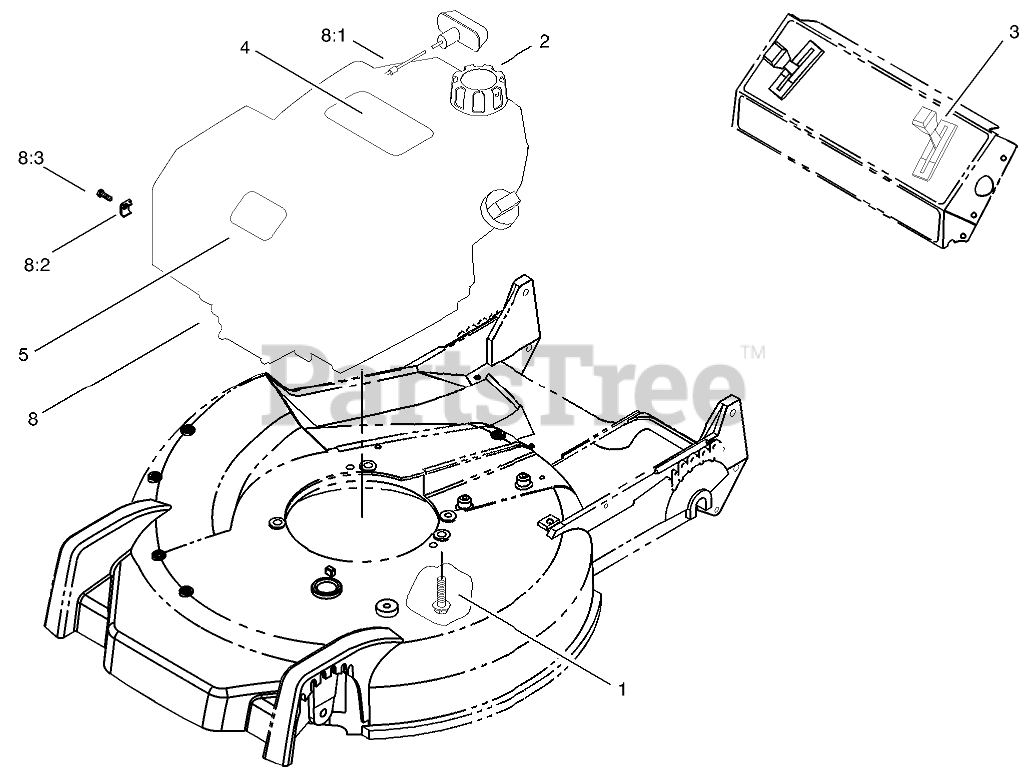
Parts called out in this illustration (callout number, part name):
1	SCREW-HWH
2	GAS CAP ASM
3	CONTROL - THROTTLE
4	DECAL - RECOIL
5	Decal
8	ENGINE - GTS OHV 200
8:1	STOP-ROPE
8:2	CLAMP-CASING
8:3	SCREW-CLAMP
